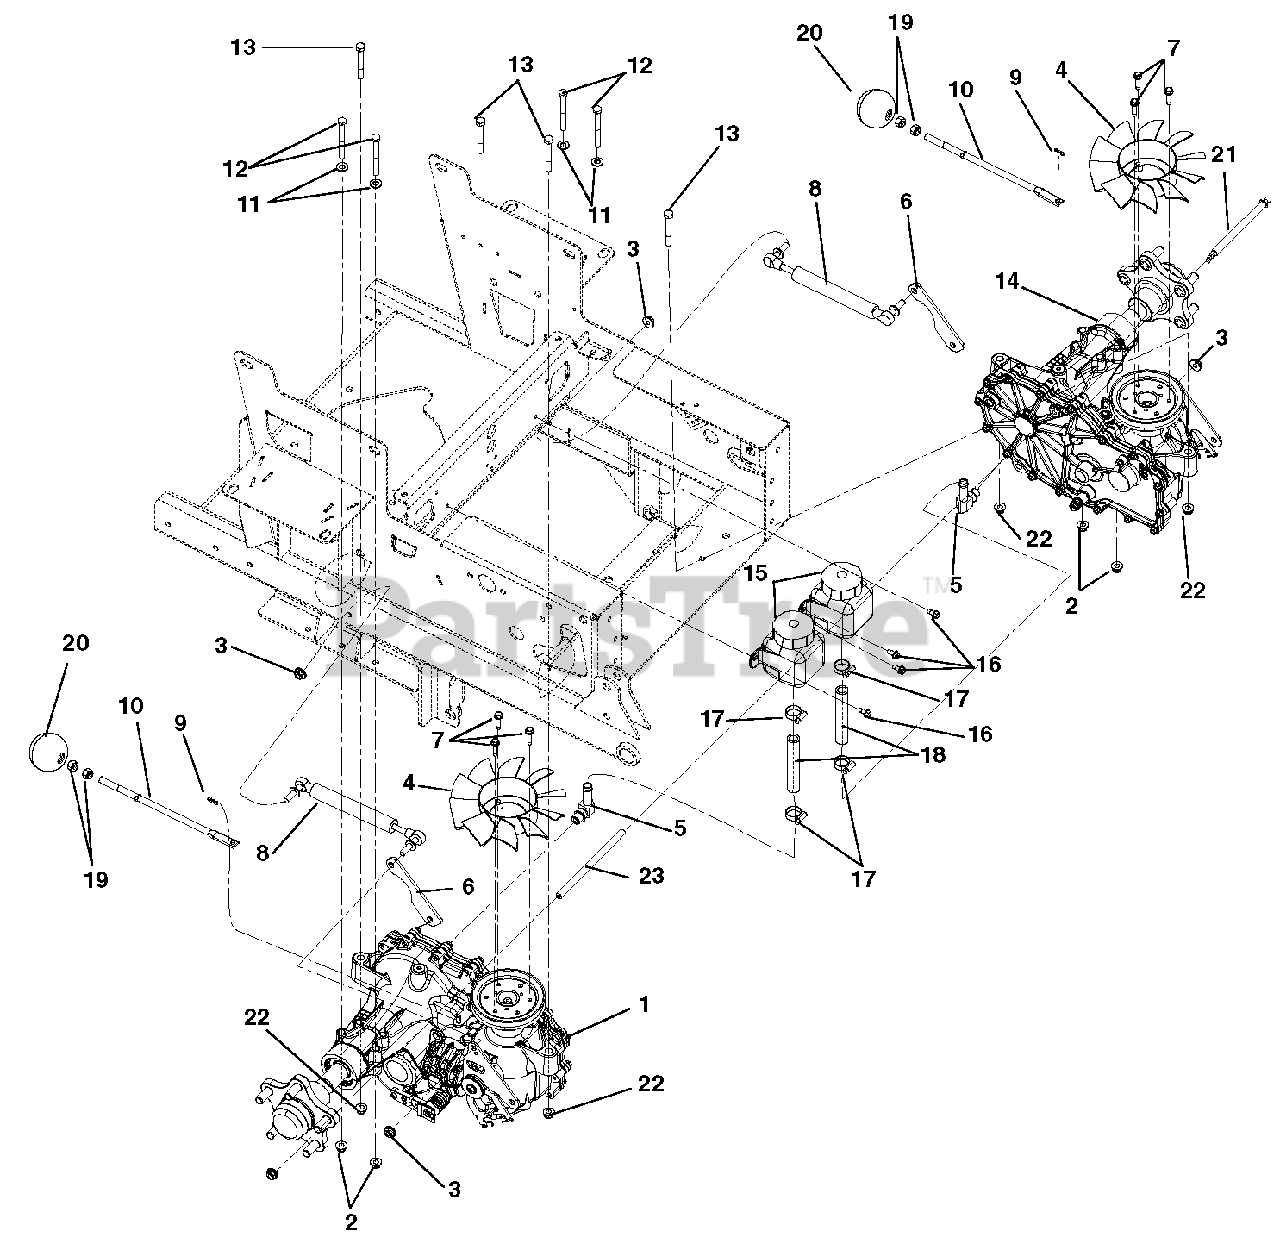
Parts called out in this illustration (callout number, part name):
1	Transaxle, 100I- Right Hand
2	Nut, .31-18 Nyloc Flange
3	Flange Patch M8-1.25
4	Fan, 2800 Series Cooling
5	Fitting, Hydraulic (90 DEG)
6	Plate, Control Reforcement
7	Screw, Tapping .25-20 x 1.00 Hex Washer Head Thread Rolling
9	Pin, Hair-Internal .06 x .18 x .77
10	Lever, 100I Dump Valve
11	Washer, Flat-Steel .344 x .688 x .065
12	Bolt, Hex .31-18 x 3.00 Grade 5
13	Bolt, Hex .38-16 x 2.50 Grade 5
14	Transaxle, 100I- Left Hand
15	Tank, Expansion ZT2800
16	Screw, Tapping .25-20 x .50 Hex Washer Head Thread
17	Clamp, .88 Diameter Hose
18	Hose, 100I Hydro Overflow
19	Nut, Jam .312-18 UNC YWZC
20	Knob, Ball Black .312-18 x 1.00
21	Bolt, Hex .38-16 x 11.00 Grade 5
22	Nut, Locking-Nylon-Flange .38-16
23	Spacer, .38 ID x 5/8 OD x 7.72
